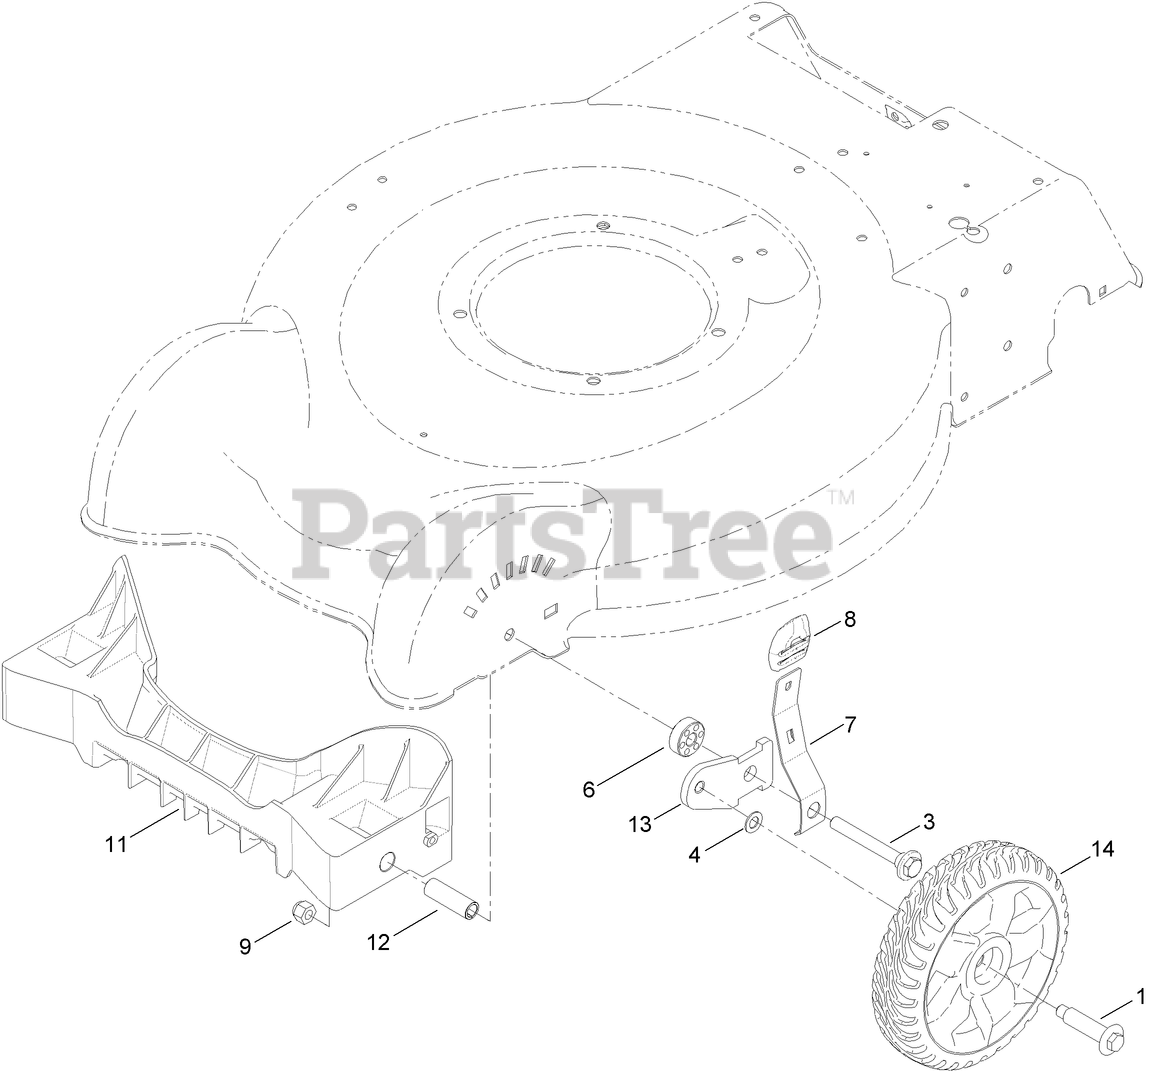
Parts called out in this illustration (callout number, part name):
1	BOLT-SHOULDER
3	BOLT-SHOULDER
6	SPACER-ARM, PIVOT
7	ARM-SPRING, FRONT
8	KNOB-LEVER, HOC
9	NUT-LOCK, NI
11	BAFFLE-THROW, FRONT
12	SPACER-BAFFLE, FRONT
13	ARM-PIVOT, FRONT (SERVICE)
14	WHEEL ASM 8", IDLER
